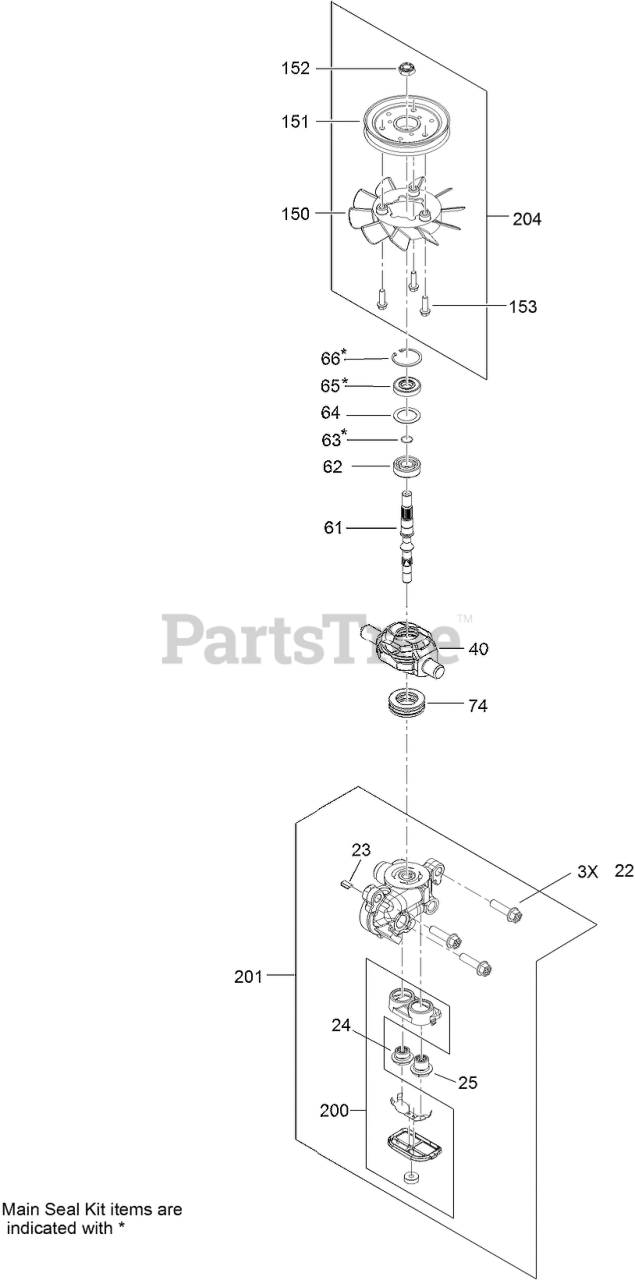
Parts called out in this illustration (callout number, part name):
22	SCREW-HFHC
23	PLATE-BYPASS
24	CHECK PLUG ASM
25	CHECK PLUG ASM
40	TRUNNION-PLATE, SWASH
61	SHAFT-INPUT
62	BEARING-BALL
63	RING-RETAINING, WIRE
64	SPACER
65	SEAL-LIP
66	RING-RETAINING
74	BEARING-THRUST, BALL
150	FAN
151	PULLEY ASM
152	NUT-HEX JAM
200	FILTER KIT
201	CENTER SECTION KIT
204	FAN PULLEY KIT
